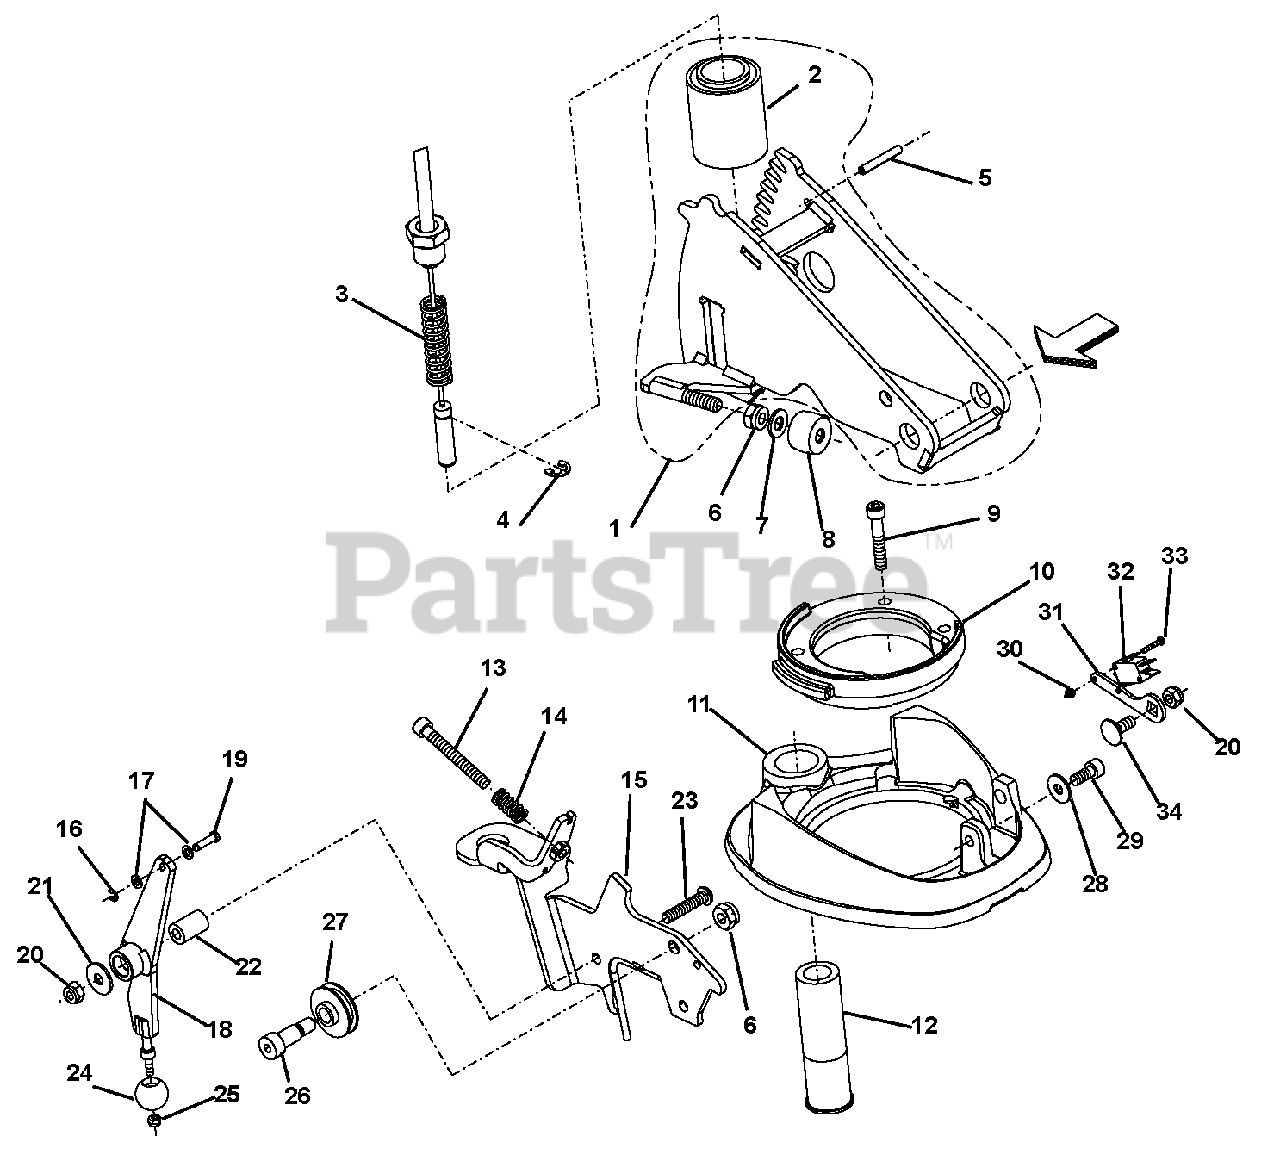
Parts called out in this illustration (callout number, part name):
1	Support Handle
2	Silentbloc
3	Spring, Pressure
4	Washer, Retaining 23 x 33 x 1.5
5	Pin, Heavy 6 x 40
6	Nut, Lock D985 M10
7	Washer, D125 10.5 x 21 x 2
8	Element, Rubber
9	Screw, Cylindrical Head,D912 M8 x 45
11	Support Handle
14	Spring, Pressure
15	Holding Sheet Metal
16	Washer, Lock 4mm
17	Washer, D125 5.3 x 10 x 1
18	Adjusting Lever
19	Pin, Lock
20	Nut, Lock, D985 M8
21	Washer, D9021 8,4 x 25 x 2
23	Screw, Countersunk Head, M8 x 40
24	Ball, Steel
25	Nut, Lock M5
26	Bolt, M10
28	Washer, M8
29	Screw, D912 M8 x 18
30	Nut, Lock D985 M3
31	Plate, Lock
32	Switch
33	Screw, Flat Head Screw D85A M3 x 18
34	Screw, Truss Head
